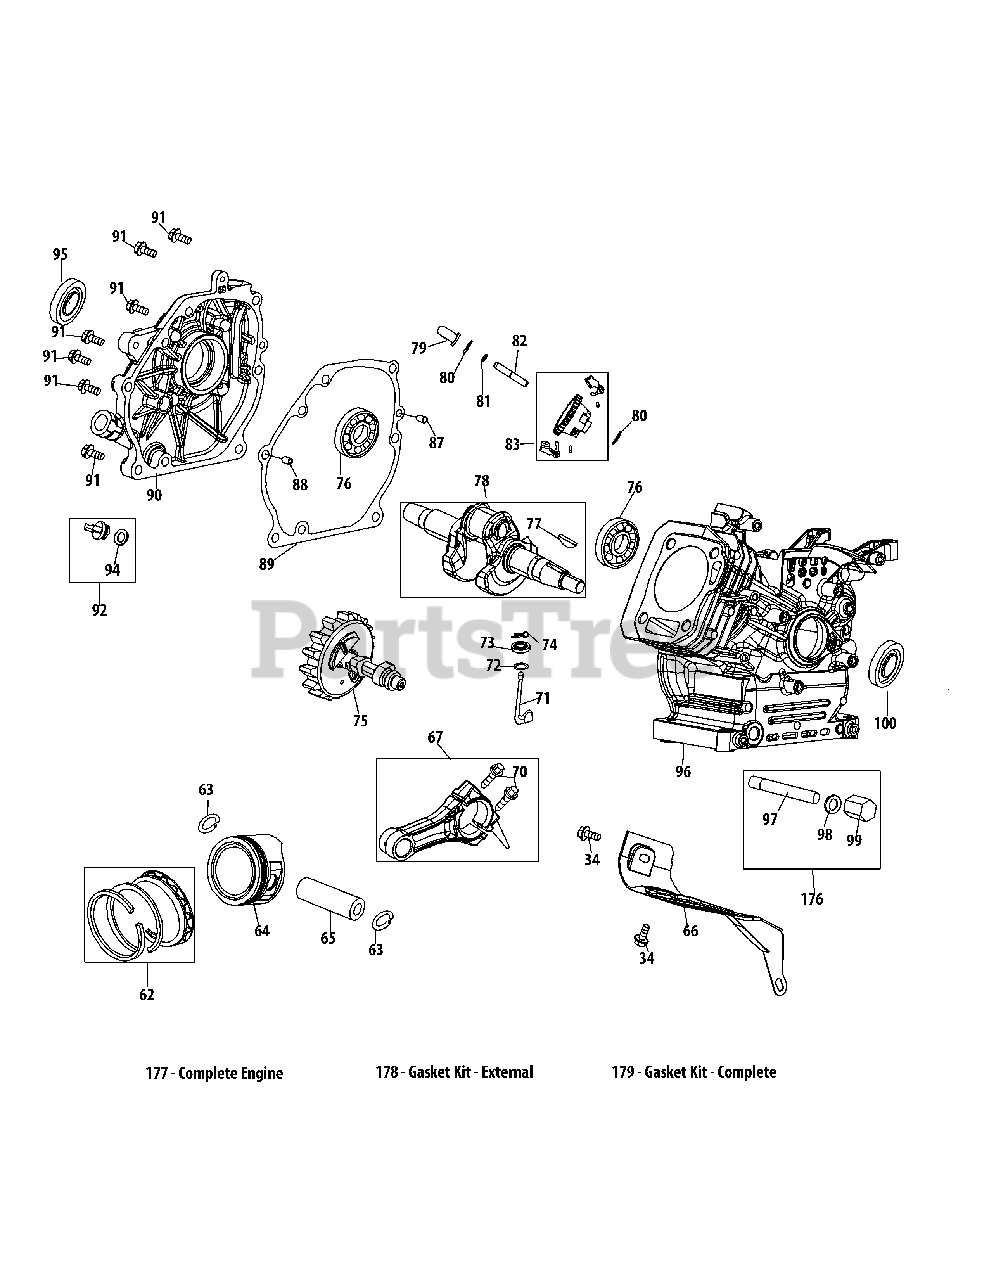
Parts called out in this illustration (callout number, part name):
34	Bolt M6×12
62	Piston Ring Set
63	Piston Pin Snap Ring
64	Piston
65	Piston Pin
66	Air Shield
67	Connecting Rod Assembly
70	Connecting Rod Bolt
71	Governor Arm Shaft
72	Washer 5.2×1.9
73	Governor Seal
74	Cotter Pin
75	Camshaft Assembly
76	Radial Ball Bearing, 6205
77	Woodruff Key
78	Crankshaft Service Kit
79	Governor Cup
80	Washer 6.2×0.6×15
82	Governor Shaft
83	Governor Body
87	Dowel Pin 7×14
88	Dowel Pin 9×14
89	Crankcase Cover Gasket
90	Crankcase Cover
90	Crankcase Cover Kit
91	Bolt M8×32
92	Oil Fill Plug Kit
94	O-Ring 15.8×2.5
95	Oil Seal, 25×41.25×6
96	Crankcase Service Kit
96	Short Block Assembly
97	Oil Drain Pipe
98	Washer 10×16×1.5
99	Oil Drain Plug
100	Oil Seal 25×41.25×6
176	Oil Drain Kit
177	Complete Engine
178	Gasket Kit - External
179	Gasket Kit - Complete
